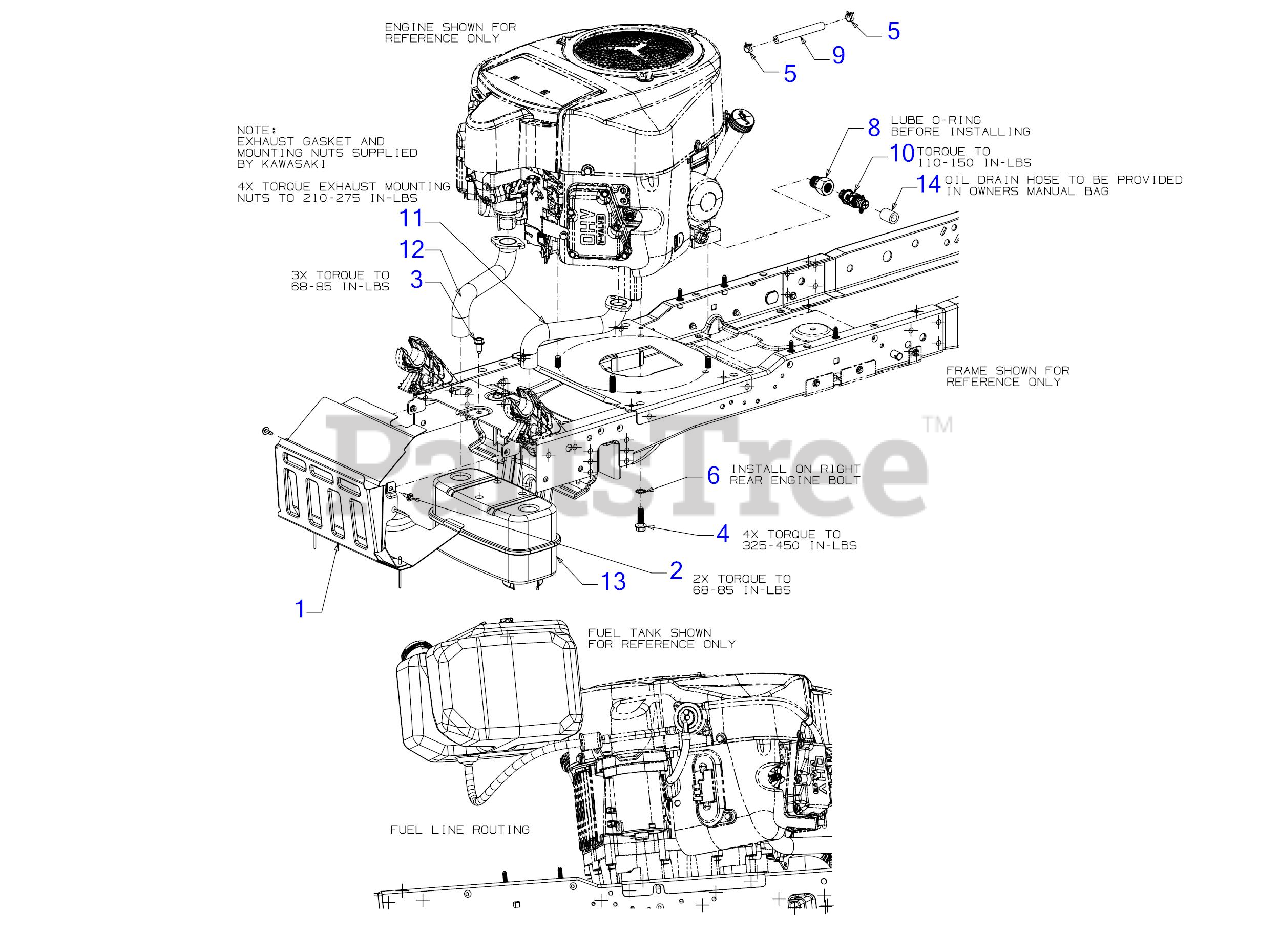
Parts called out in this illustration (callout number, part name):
1	MUFFLER SHIELD ASSEMBLY
2	SCREW M6-1 x .625
3	SCREW M8-1.25 x .750
4	SCREW 3/8-16 X1.250
5	HOSE CLAMP 1/20
6	LOCK WASHER 3/8
8	OIL DRAIN FITTING
9	FUEL HOSE LOW PERMEATION
10	OIL DRAIN VALVE
11	EXHAUST PIPE (LH) (KAWASAKI)
12	EXHAUST PIPE (RH) (KAWASAKI)
13	EXHAUST MUFFLER (TWIN)
14	DRAIN HOSE 14''
